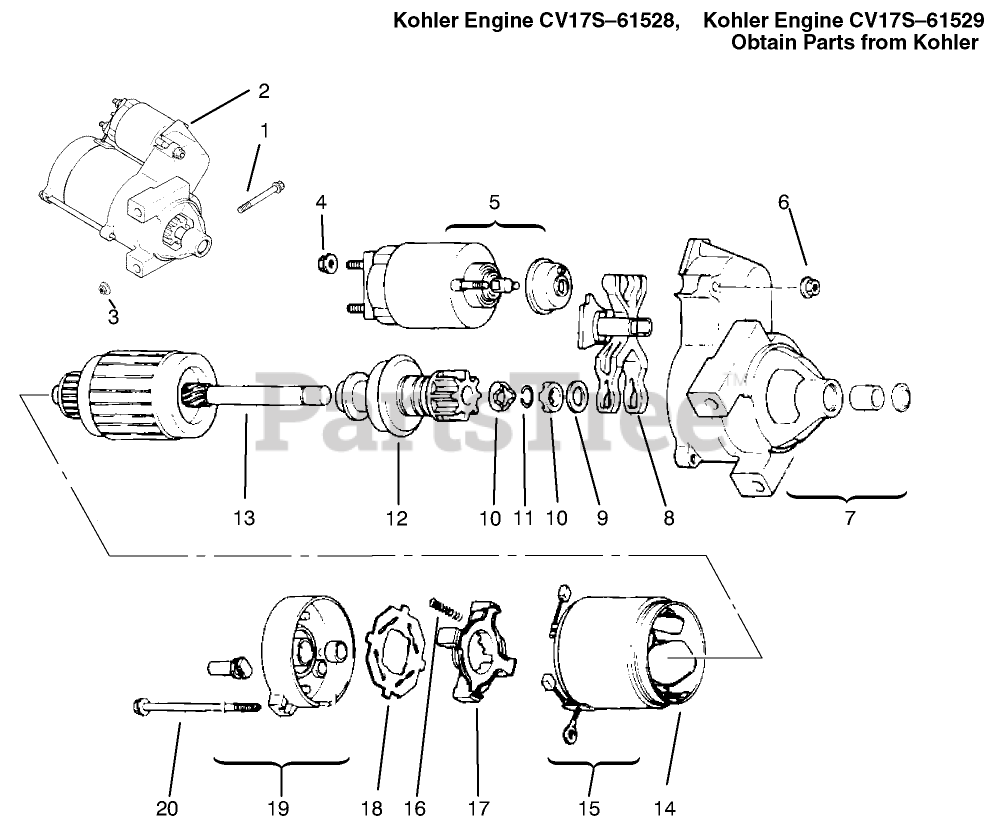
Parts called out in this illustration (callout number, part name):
1	Screw M8x1.25x80 (Only On: 72103, 72083)
2	Starter-Solenoid Shift (Incl. Ref. # 4-20)
4	Nut
5	Solenoid
6	Nut Starter
7	Cap-Drive End
8	Lever Starter Drive
9	Washer-Thrust (Only On: 72103, 72083)
10	Nut-Stop Collar
11	Ring-Retainer
12	Drive-Pinion
13	Armature-Starter
14	Frame
15	Kit-Brush (Incl. Ref. # 16)
16	Spring-Brush
17	Holder-Brush
18	Insulator
19	Cap-Commutator End
20	Bolt
